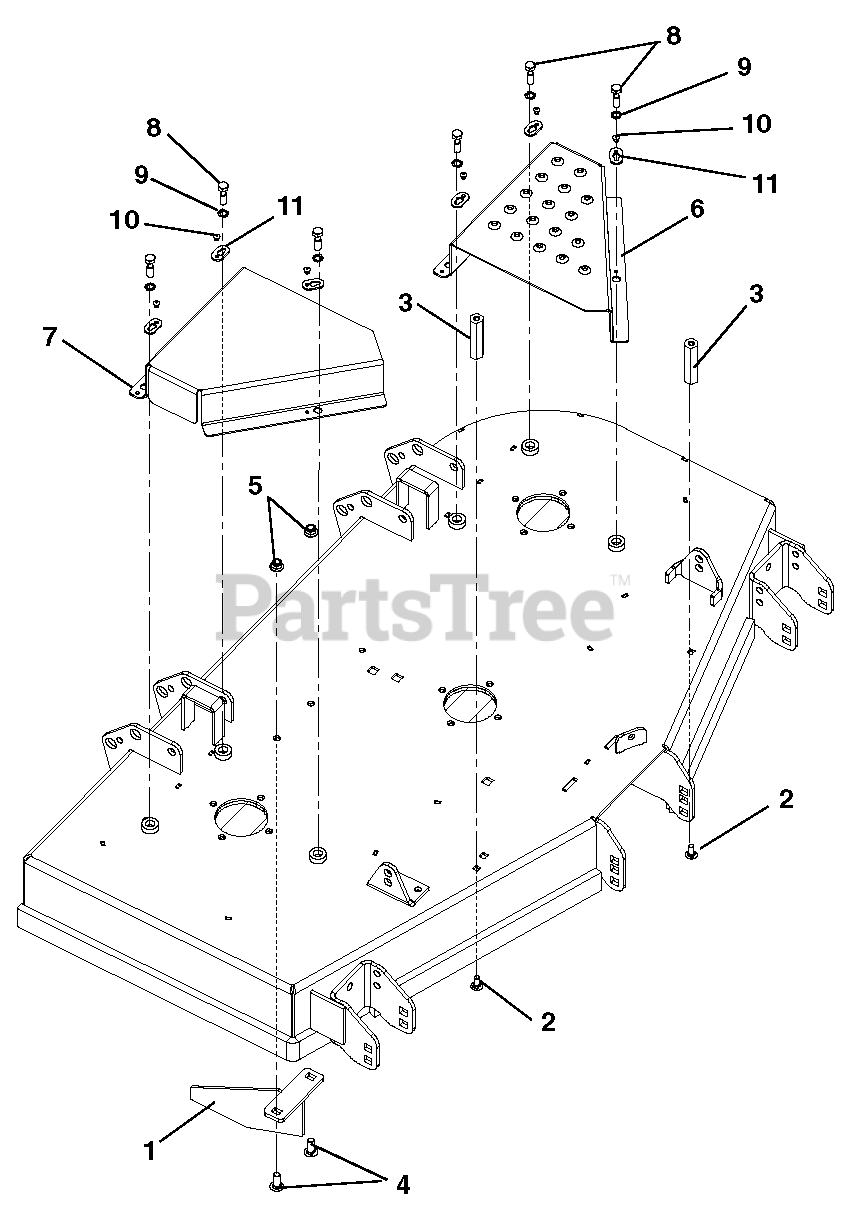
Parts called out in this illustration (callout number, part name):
1	Rear Discharge Deflect Baffle Weldment
2	Bolt, Round Head Square Neck .31-18 x .75
3	Nut, Coupling .31-18 x 3.00
4	Bolt, Round Head Square Neck .38-16 x 1.00 Grade 5
5	Nut, Locking-Nylon-Flange .38-16
6	Cover, Left Hand PT200 Belt, CE
7	Cover, Right Hand PT200 CE Belt
8	Bolt, Hex .38-16 x 1.25 GRADE 5
9	Washer, Locking-EXT.391 x .682 x .036
10	Rivet, Pop .187
11	Keeper, Bolt
